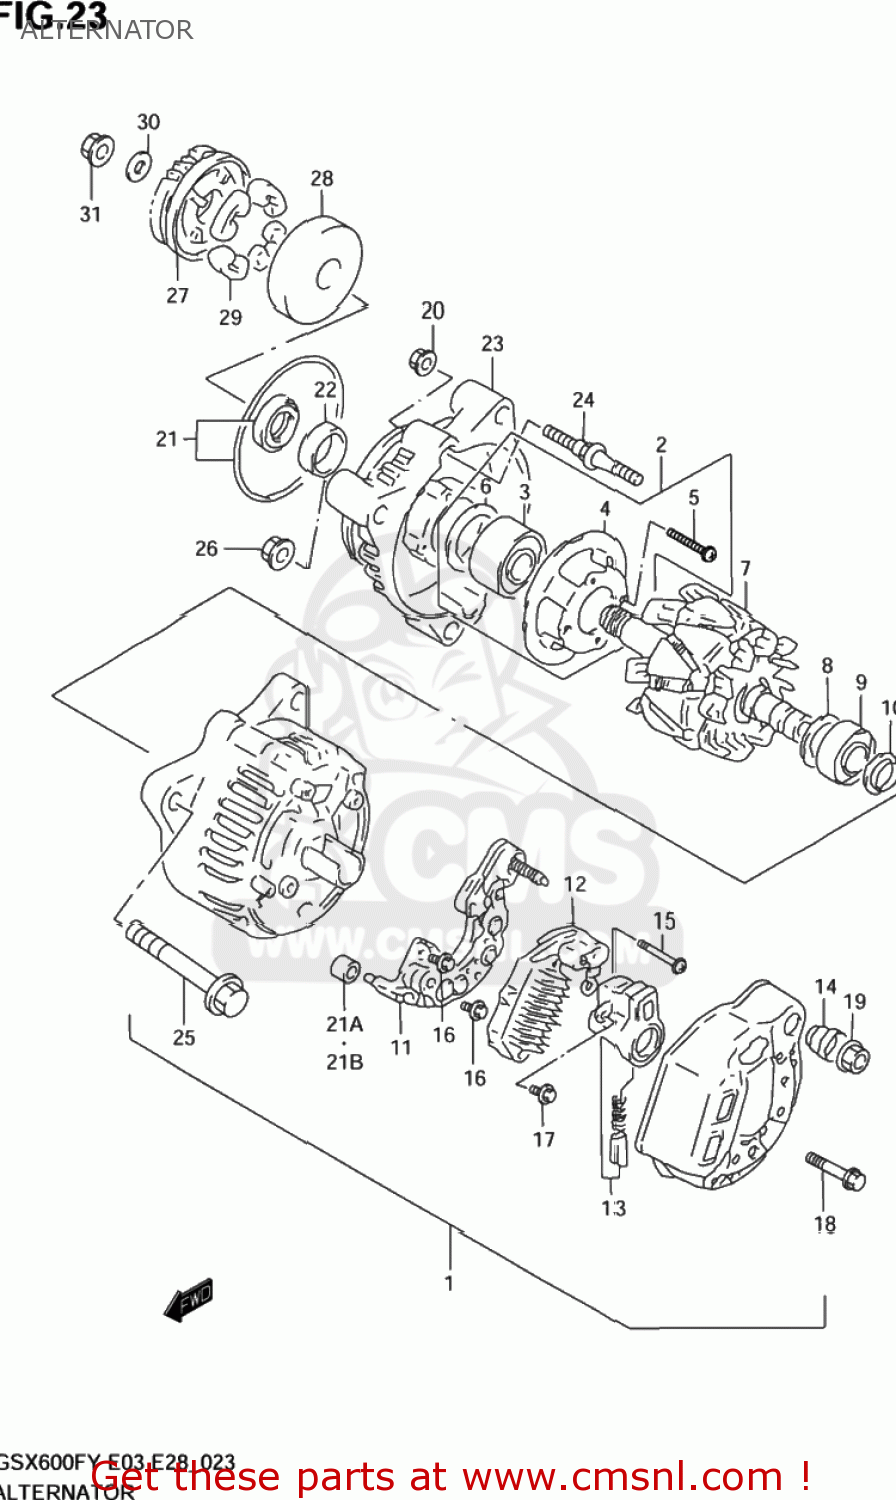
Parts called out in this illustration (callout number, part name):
1	ALTERNATOR ASSEMBLY
2	FRAME,DRIVE END
3	BEARING
4	RETAINER
5	SCREW(4X14)
6	COVER,BEARING
7	ROTOR ASSY
8	COVER,BEARING
9	BEARING
10	COVER(2)
11	HOLDER,RECTIFIER
12	REGULATOR ASSY
13	HOLDER,BRUSH
14	INSULATOR,TERMINAL
15	SCREW
16	SCREW 4X6
17	SCREW
18	SCREW
19	NUT
20	NUT
21	SERVICE KIT(A)
21A	SERVICE KIT,B
21B	SERVICE KIT(B)
22	SPACER
23	FRAME,END
24	STUD BOLT
25	BOLT
26	NUT
27	GEAR,GENERATOR DRIVEN
28	HOUSING,GENERATOR GEAR DAMPER
29	DAMPER,GENERATOR DRIVEN
30	WASHER
31	NUT
